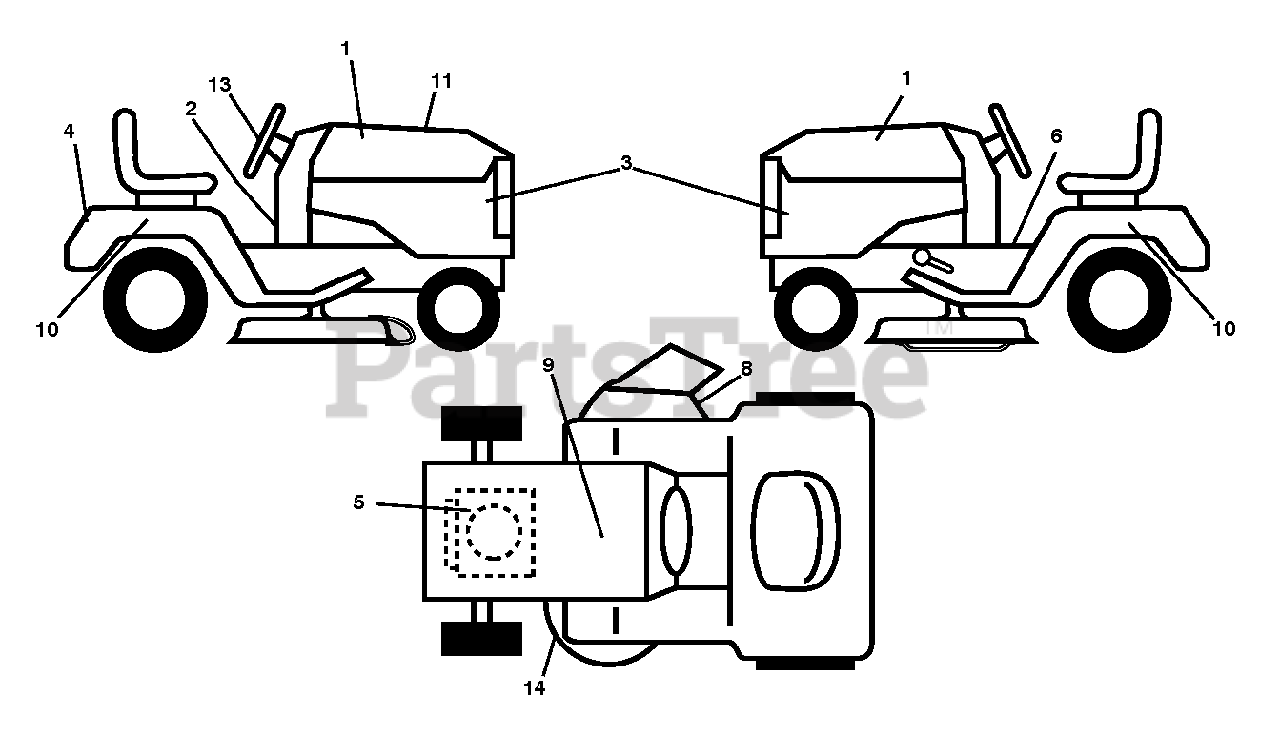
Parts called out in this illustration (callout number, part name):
1	DECAL.HOOD.POULAN.PRO.SET
2	DCL.WARNING.SPARK.IGNITION.CA
3	DECAL.SDPNL.RH/LHPAIR.20A46YT
5	Decal, Engine BS 20INTK DOM 381707
6	DECAL.WARNING.2007.ENG/FR
8	DECAL.WARN.KEEP.HAND.AWAY
9	DECAL BTRY SYMBOLS
10	DECAL.SDFNDR.TX.AUTO.EN/FR.SET
11	DECAL DECAL.RPL.BSM40.INTK.TLW
13	DECAL.STEER.WHEEL.POULAN.PRO
14	DECAL.V-BELT.SCH.42/46"MEC/ELE
